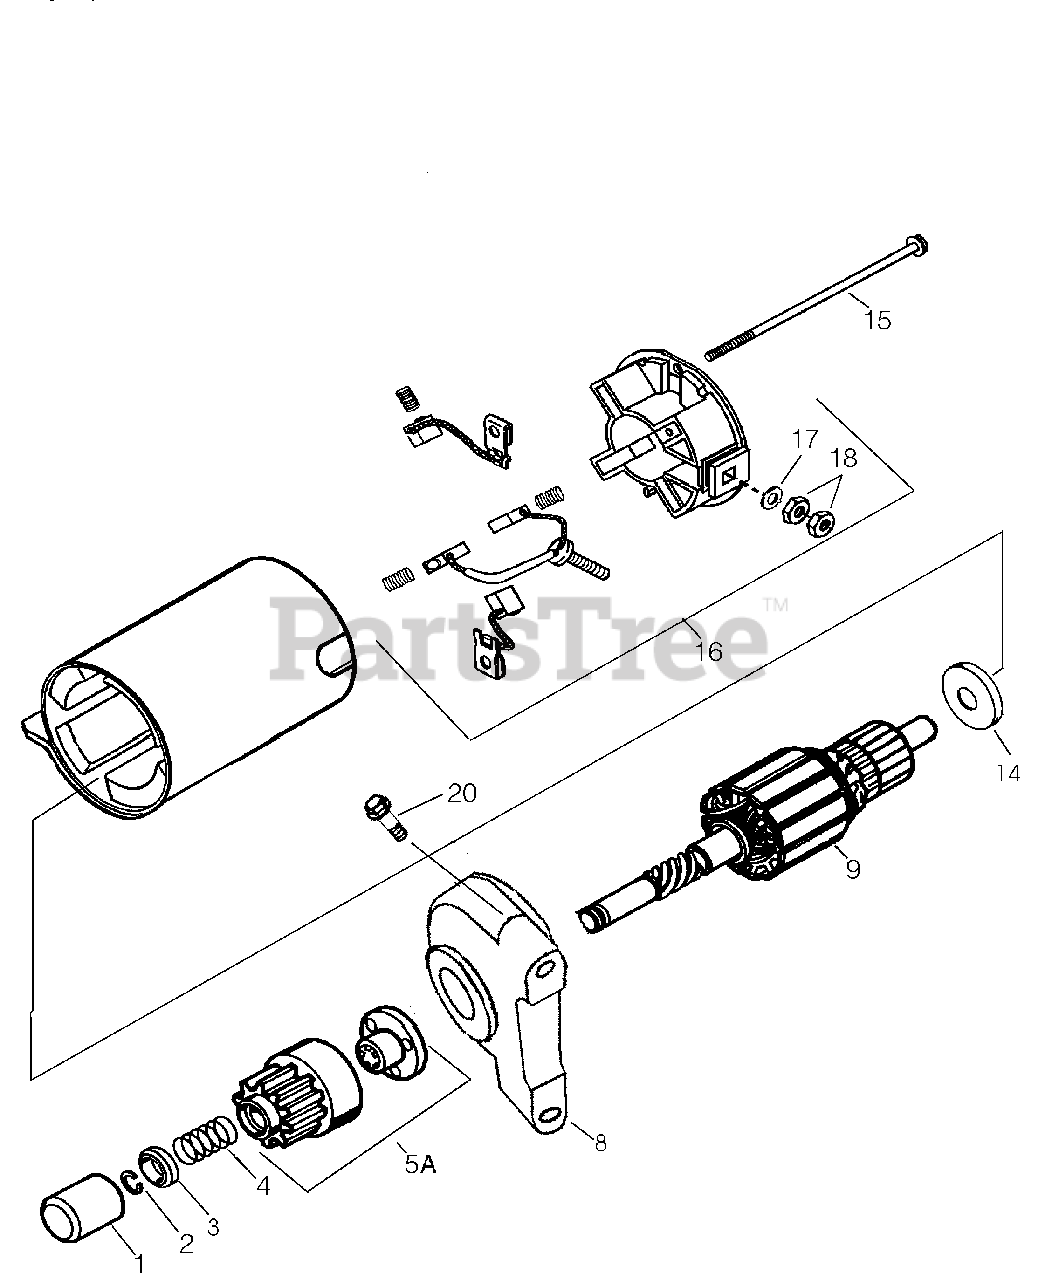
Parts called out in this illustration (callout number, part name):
1	Dust Cover
2	Retainer Ring
3	Spring Retainer
4	Anti-drift Spring
5A	Gear & Nut (Incl. 2)
8	Drive End Cap Assembly
9	Armature
14	Thrust Washer
15	Case Bolt
16	End Cap & Brush Card Ass'y Incl. 14,1 7 & 18
20	Screw, 1/4-20 x 1-13/32
